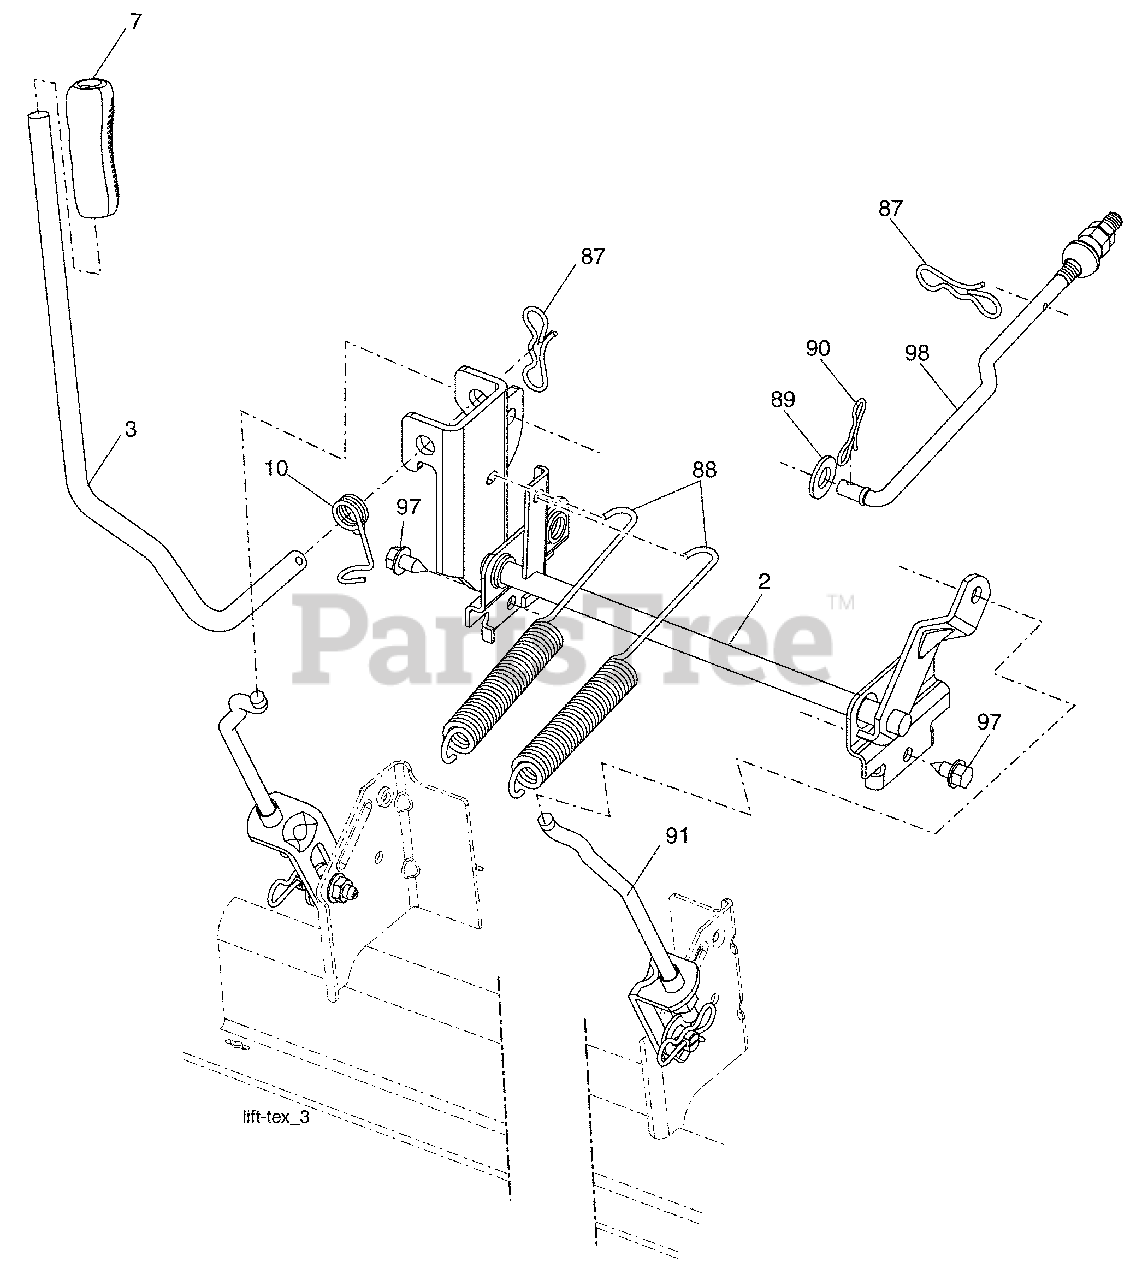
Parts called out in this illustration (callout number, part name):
2	Shaft Asm., Lift
3	Lever Asm., Lift Rh
7	Grip, Lever
10	Spring Torsion
41	Nut, 7/16-20
87	Pin Cotter 7/16 Bow Tie Lock
88	Spring Lift Assist
89	Washer Clear Zinc
90	Pin Cotter 5/16 Bow Tie Lock
91	Link Lift Susp Mower Rear
92	Bracket Connect Link Lift
95	Bushing Alignment Link Lift
97	Screw 3/8-16 x .75 Smgml Tap/R.Z
98	Link Lift Susp. Front Mower
99	Bushing Spherical Susp Front
100	Nut Hex Jam ASF 7/16-20 unf
